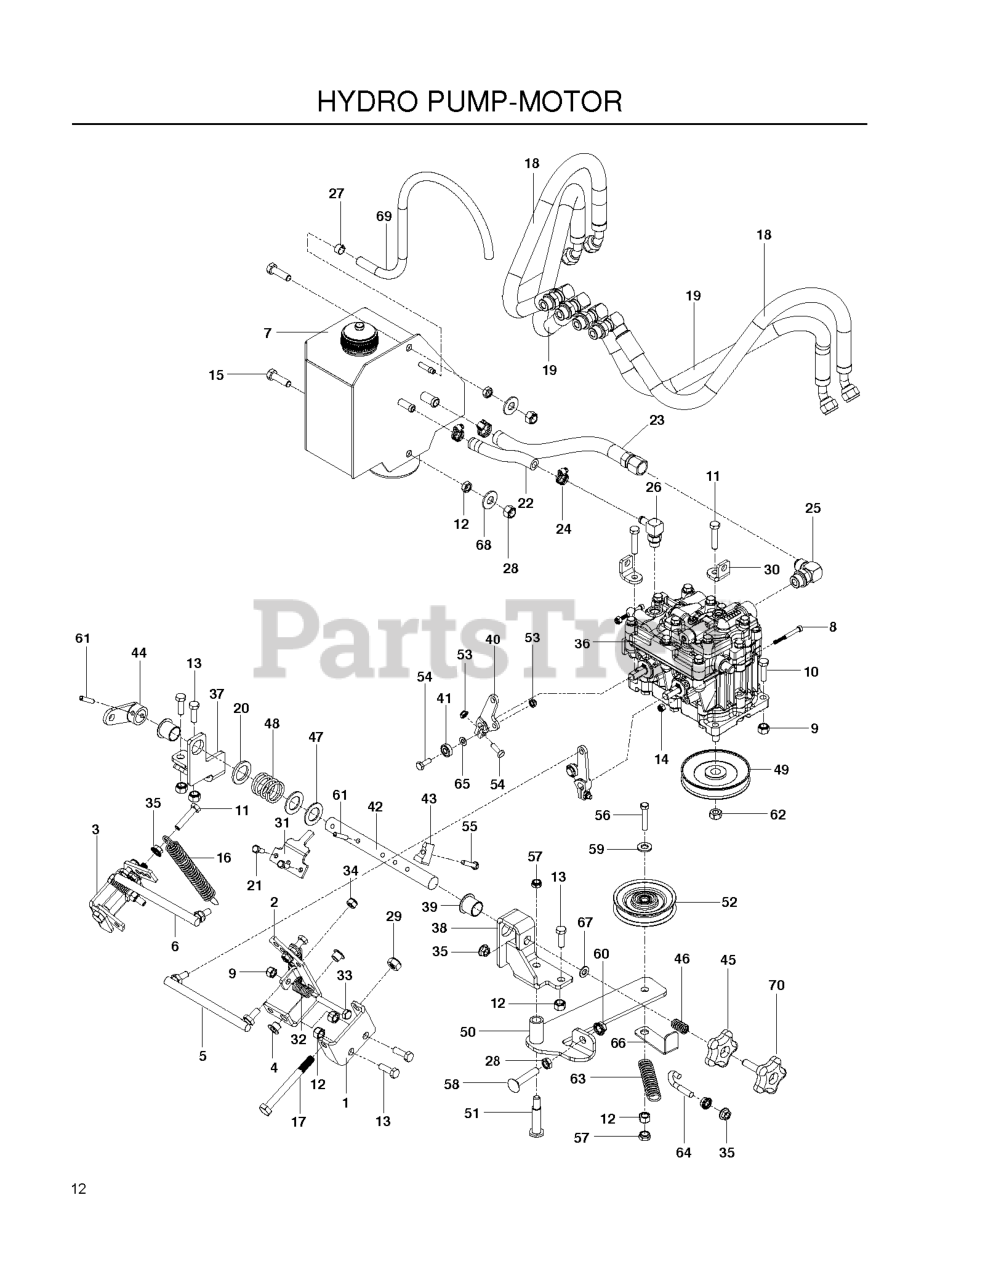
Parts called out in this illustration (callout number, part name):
1	BRACKET - U
2	BELLCRANK LH PAINTED
3	BELLCRANK RH PAINTED
4	BEARING - FLANGE 10MM
5	LINK - CONTROL, RH WB
6	LINK - CONTROL, LH WB
8	SCR, #10-24X2 SOCKET HEAD CAP
9	NUT 5/16 NYLOC
10	HCS 5/16C X 1 1/4
11	CAPSCREW 5/16 X 1/1/2 HEX HEAD
12	NUT 3/8-16 NYLOC
13	HCS 3/8-16 X 7/8 GR 5 ZD
14	NUT 10-24 NYLOC
15	HCS 3/8C X 1 1/4 GR5
16	SPRING-TRANS
17	HCS M10-1.58 X 100MM GR8.8 ZD
20	WASHER, FIBER
21	HCS M6-1.0 X 16MM GR 8.8 ZN
22	HOSE - RETURN
23	HOSE - SUCTION
24	HOSE CLAMP T-1865
25	ELBOW, 90 DEGREE
26	FITTING, 90 DEG 9/16-18 X 3/8
27	HOSE CLAMP
28	NUT 3/8-16 HEX JAM
29	NUT, M10-1.5 NYLON RING ZD
30	BRACKET, SPRING, BLK
31	PLATE - STOP, BLK
33	HCS 5/16-18X2
34	NUT M8-1.25 TOP NYL GR10 ZD
35	NUT 5/16C WHIZ
36	PUMP, DUP10E
37	SUPT - CAM LH
38	SUPT - CAM, RH PAINTED
39	BEARING - FLANGE, 20MM
40	ARM - HYDRO
41	BEARING - FOLLOWER
42	SHAFT - CAM
43	CAM - TRACKING
44	ARM - SPEED CONTROL
46	SPRING - COMPRESSION
47	WASHER - 20MM
48	SPRING - COMPRESSION
49	PULLEY, PUMP
51	BOLT, SHOULDER
53	JAM NUT 1/4C (2 2 PW01)
54	HCS 1/4C X 3/4 HCS
55	BOLT - M6-1.0 X 30MM GR 8
56	HCS 3/8C X 2
57	NUT HEX 3/8-16 NYLON, THIN
58	RHSNB 3/8C X 2
59	WASHER 3/8 SAE FLAT
60	NUT 3/8C WHIZ
61	ROLL PIN - 6 MM X 30 MM
62	NUT M10-1.5 L/H HEX
63	SPRING AXLE AERATOR
66	KEEPER, BLK
67	FLAT WASHER 5/16 SAE
68	WASHER 3/8 FLAT
70	KNOB, ADJUSTING
